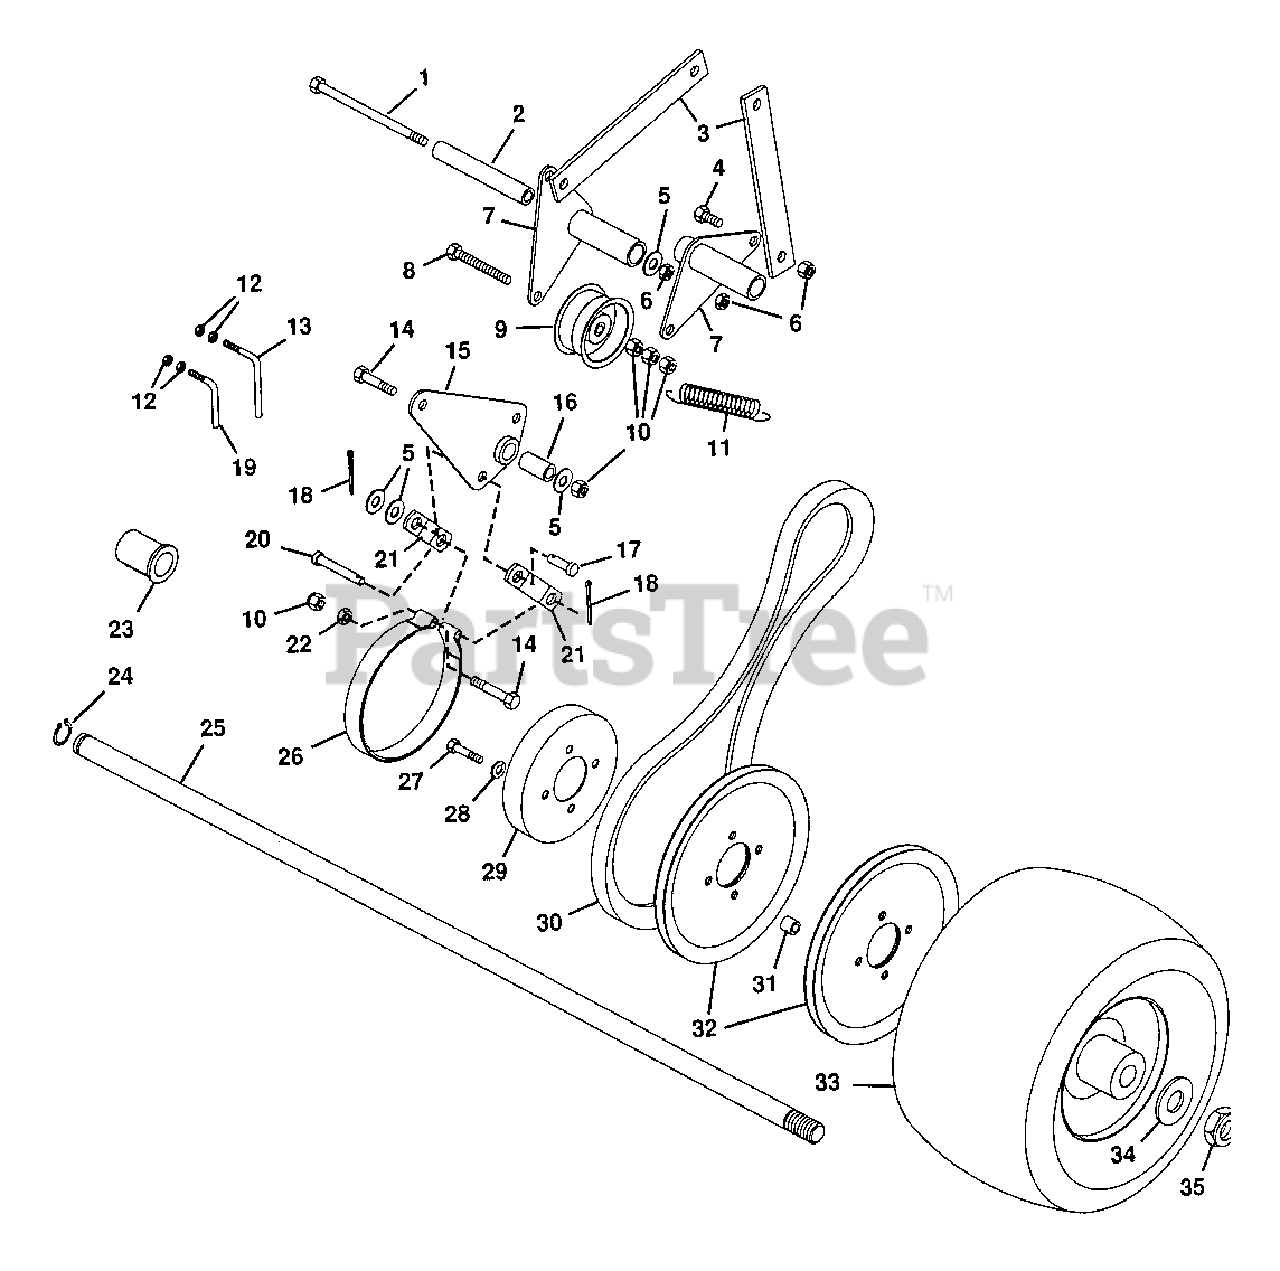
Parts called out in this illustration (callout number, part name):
1	Bolt, Hex 3/8-1660
2	Bushing, St. .385 x.610 x3.85 Stl.
3	Strap, Wheel Clutch
4	Bolt, Hex 3/8-16x.75
5	Washer, Flat .406x.812x.065
6	Nut, Lock 3/8-16
7	Weldment, Wheel Clutch Arm
8	Bolt, Hex 3/8-16x3.00 All Thread
9	Sheave, Idler
10	Nut, Lock 3/8-16
11	Spring, Clutch Idler
12	Nut, Hex 1/4-20
13	Rod, Pulley Cleaning
14	Bolt, Hex 3/8-16x1.75
15	Weldment, Brake Arm
16	Bushing, St. .391 x.622x.950 Stl.
17	Pin, Clevis 3/8x.594
18	Pin, Cotter .12505
19	Rod, Pulley Cleaning
20	Pin, Clevis 3/8x1.093
21	Link, Brake Arm
22	Nut, Hex 3/8-16
23	Bushing, Flange
24	Ring, Retaining
25	Shaft, Axle
26	Assembly, Brake Band
27	Bolt, Hex 5/16-18x1.50
28	Washer, Lock 5/16 Reg,
29	Drum, Brake
30	Belt, Vee Drive Wheel (Set of 2)
31	Bushing, St. .385x.625x.475 Stl.
32	Pulley, Pro Drive Wheel
33	Assembly, Wheel 13x8.50-6
34	Washer, Flat .813x1.37x.100
35	Nut, Lock 3/4-10 Light Thin
